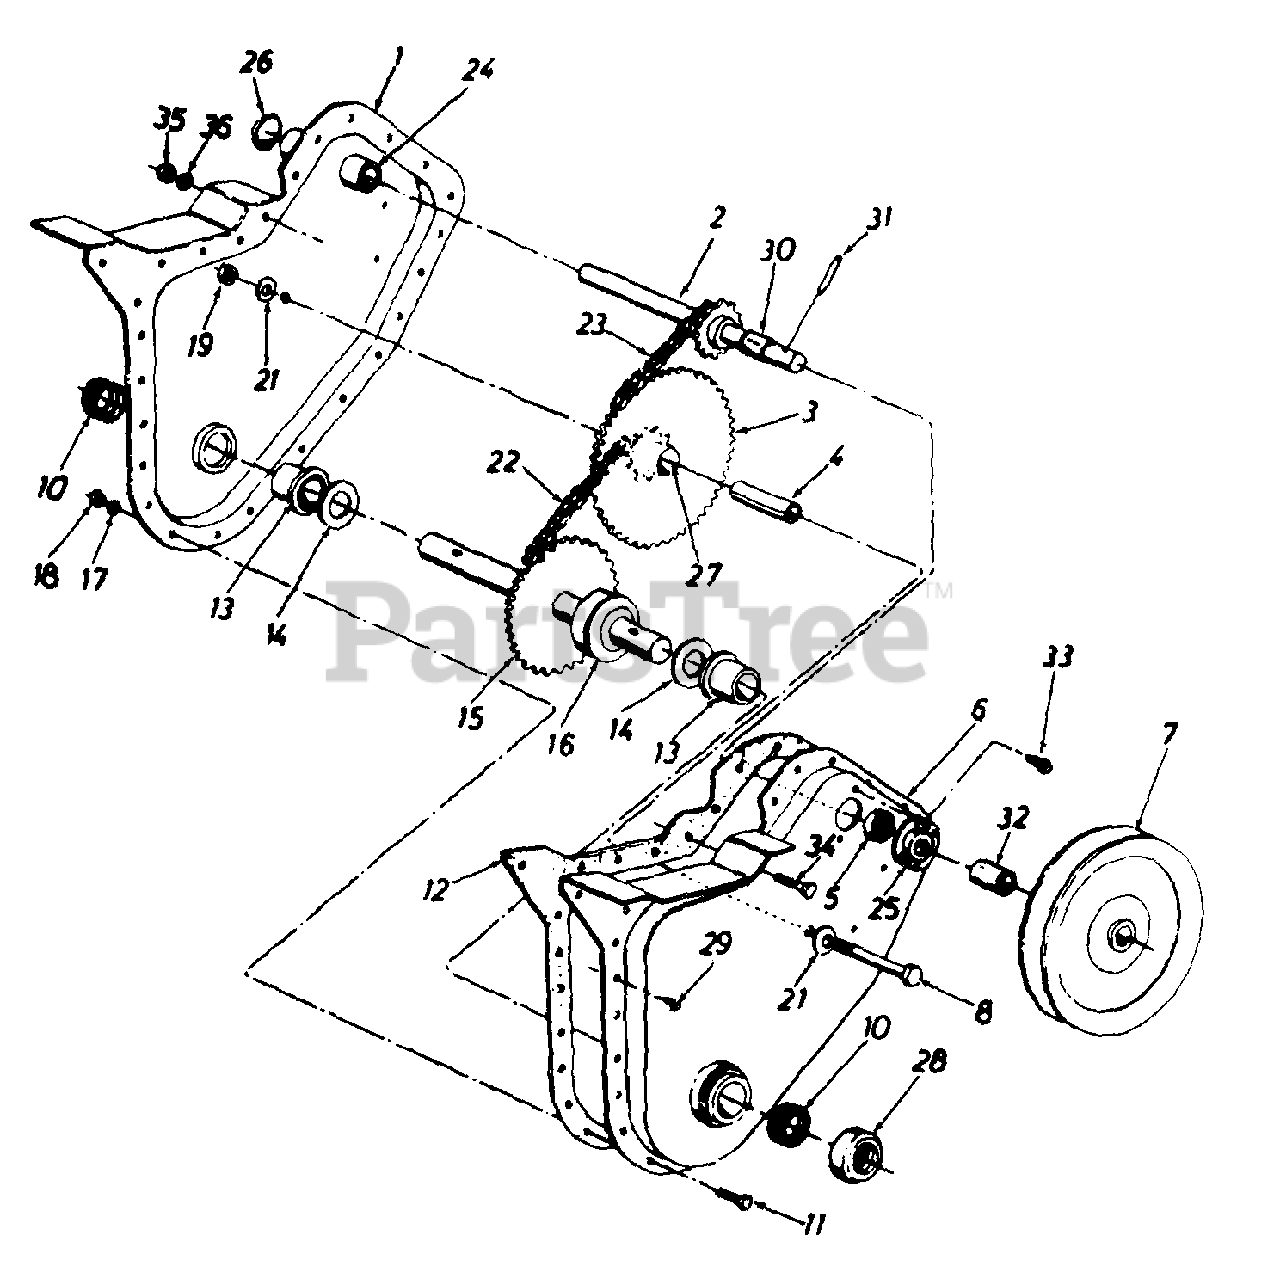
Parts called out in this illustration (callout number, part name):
1	Chain Case Ass'y, - R.H.
2	Input Shaft Ass'y.
3	Hub and Sprocket Ass'y.
4	Bearing Inner Race
5	Ball Bearing
8	Hex Bolt 3/8-24 x 2.5"
10	Seal
11	Hex Bolt 1/4-28 x .625"
12	Gasket
13	Flange Brg. .879" I.D.
14	Fl-Wash. .88" I.D. x 1.5"
15	Tine Shaft Ass'y.
16	Spacer 7/8" I.D.
17	L-Wash. 1/4" I.D.
18	Hex Nut 1/4-28 Thd.
19	Hex Ins. L-Nut 3/8-24 Thd.
21	Bell-Wash. .406" I.D.
22	Chain #420 1/2" Pitch 38 Links
23	Chain #35 .375" Pitch 50 Links
24	Bearing .62" I.D. x .813"
25	Bearing Housing
26	Expansion Plug 13/16" Dia.
27	Bearing
28	Dust Cap
29	Hex Wash. Hd. Self-Tap Scr. 1/4-20 x .50" Lg.
30	Spacer .63" I.D. x .77" O.D. x .38" Lg.
31	Spring Pin Spiral 1/4" Dia. x 1-1/2" Lg.
32	Spacer .647 x 1.25"
33	Hex Wash. Hd. Self-Tap Scr. 1/4-20 x .38" Lg.
34	Hex Bolt 5/16-18 x .75" Lg.
35	Hex Nut 5/16-18 Thd.
36	L-Wash. 5/16" I.D.
